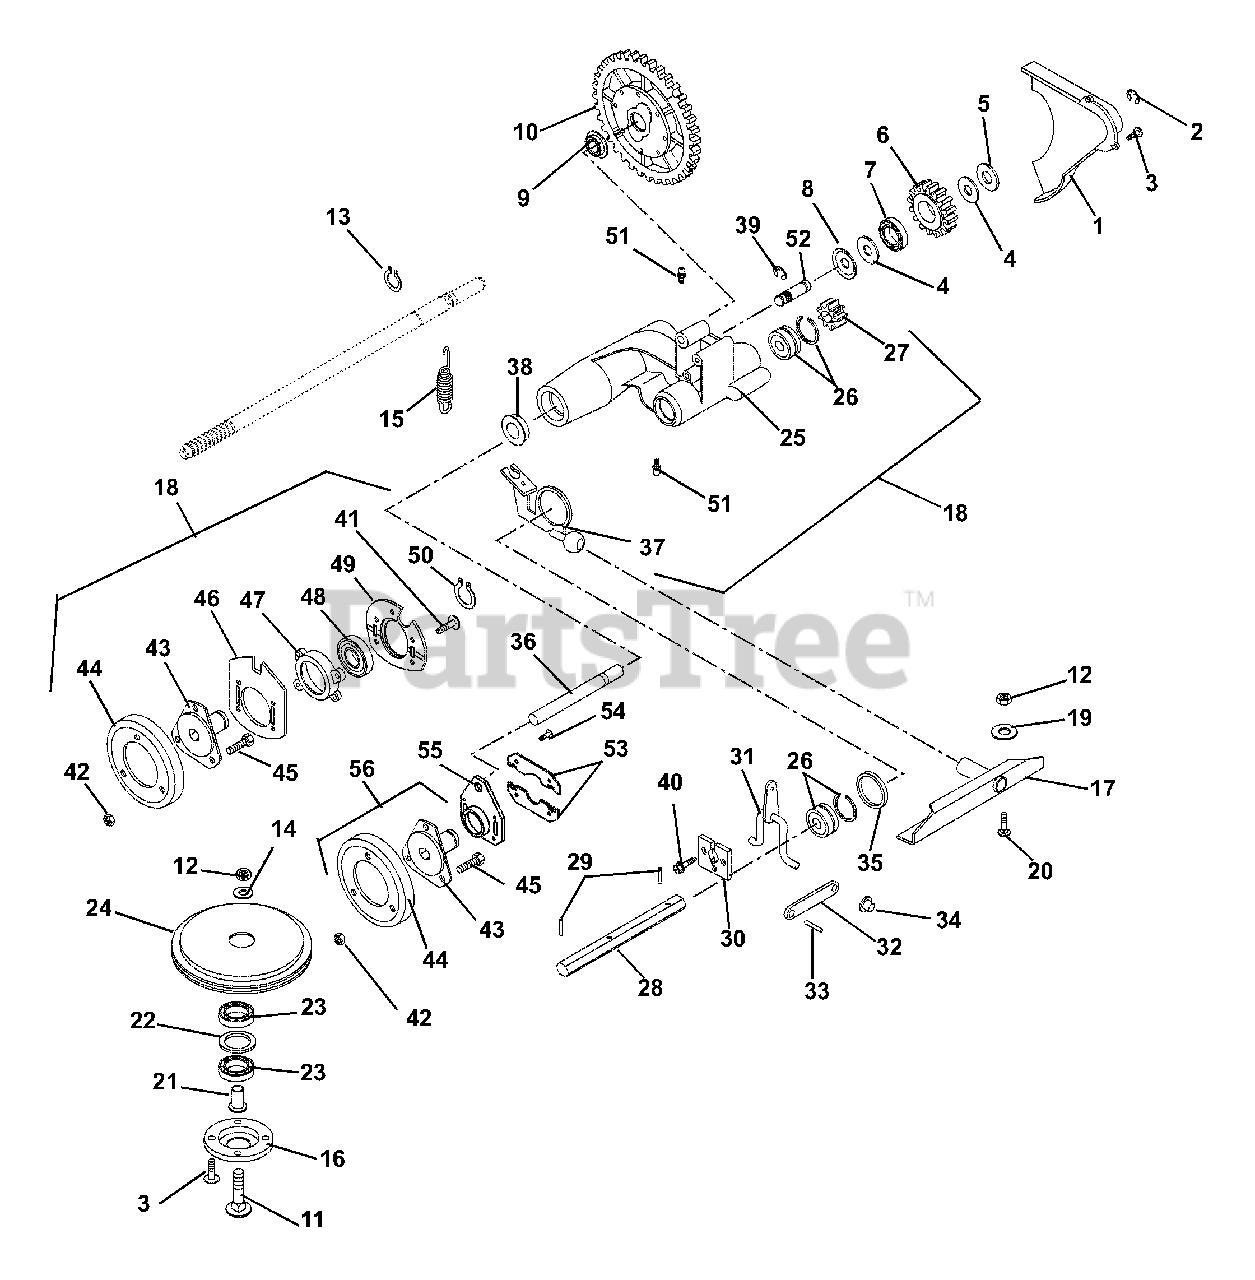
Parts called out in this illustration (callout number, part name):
1	Gear Cover
2	Ring, Retaining External .438 x .035
3	Screw, Tapping 12-24 x .50 Hex Washer Head
4	Washer, Flat Steel .520 x .827 x .062
5	Washer, Flat Steel .531 x 1.00 x .063
6	Idler Gear
7	Bearing, Ball .50 x 1.38 x .437
8	Retainer
9	Bearing, Ball .625 x 1.38 x .50 (094, 394)
9	Bearing, Ball .625 x 1.38 x .50 (911098 s/n 281 & up; 911100 s/n 560 & up)
9	Bearing, Ball .625 x 1.378 x .44 (911098 s/n 101-280; 911100 s/n 101-559)
10	Differential Assembly
11	Bolt, Round Head Square Neck .31-18 x 1.75 Grade 5
12	Nut, Locking Center .31-18
13	Ring, Retaining External .579 x .035
14	Washer, Flat Steel .38 x .87 x .179
15	Spring, Tension .051 x .60 x 2.25
16	Bearing, Retainer
17	Pivot Channel Weldment
18	Kit, LM Drive Carrier
19	Washer, Flat Steel .344 x .688 x .065
20	Bolt, Round Head Square Short Neck .31-18 x .62
21	Spindle, Bearing
22	Washer, Flat Steel 1.062 x 1.344 x .032
23	Bearing, Ball .625 x 1.375 x .43
24	Friction Sheave
25	Drive Carrier (094, 394)
25	Drive Carrier (911098 s/n 281 & up; 911100 s/n 560 & up)
25	Drive Carrier (911098 s/n 101-280; 911100 s/n 101-559)
26	Bearing, Ball .562 x 1.375 x .437
27	Gear, Pinion
28	Hex Shaft
29	Pin, Roll .188 x .88
30	Retainer Plate
31	Shift Arm Weldment
32	Shift Link
33	Pin, Roll .125 x .50
34	Push Nut .25
35	Washer, Flat Steel 1.39 x 2.00 x .02
36	Rod, Guide
37	Drive Actuator Weldment
38	Bearing, Ball .625 x 1.38 x .50
39	Ring, Retaining External .438 x .035
40	Screw, Tapping 12-24 x .50 Hex Washer Head
41	Screw, Hex Flange Washer Head Tapping 5MM-0.8 x 16MM (094, 394)
41	Screw, Hex Flange Washer Head Tapping 5MM-0.8 x 16MM (911098 s/n 281 & up; 911100 s/n 560 & up)
42	Nut, Locking Center .25-20
43	Hub, Friction Wheel
44	Disc, Friction
45	Bolt, Hex .25-20 x .50 Grade 5
46	Plate, Bearing (094, 394)
46	Plate, Bearing (911098 s/n 281 & up; 911100 s/n 560 & up)
47	Bearing Retainer (094, 394)
47	Bearing Retainer (911098 s/n 281 & up; 911100 s/n 560 & up)
48	Bearing Ball 1.00 x 2.00 x .56 (094, 394)
48	Bearing Ball 1.00 x 2.00 x .56 (911098 s/n 281 & up; 911100 s/n 560 & up)
49	Bearing Retainer (094, 394)
49	Bearing Retainer (911098 s/n 281 & up; 911100 s/n 560 & up)
50	Ring, Retaining External 1.00 x .042 (094, 394)
50	Ring, Retaining External 1.00 x .042 (911098 s/n 281 & up; 911100 s/n 560 & up)
51	Fitting, Lube .25-28 x .256 (094, 394)
51	Fitting, Lube .25-28 x .256 (911098 s/n 281 & up; 911100 s/n 560 & up)
52	Idler Shaft
53	Plate, Thrust (911098 s/n 101-280; 911100 s/n 101-559)
54	Screw-Tapping 10-24 x .375 Hex Washer Head (911098 s/n 101-280; 911100 s/n 101-559)
55	Plate, Guide (911098 s/n 101-280; 911100 s/n 101-559)
56	Assembly, Friction Wheel (911098 s/n 101-280; 911100 s/n 101-559)
